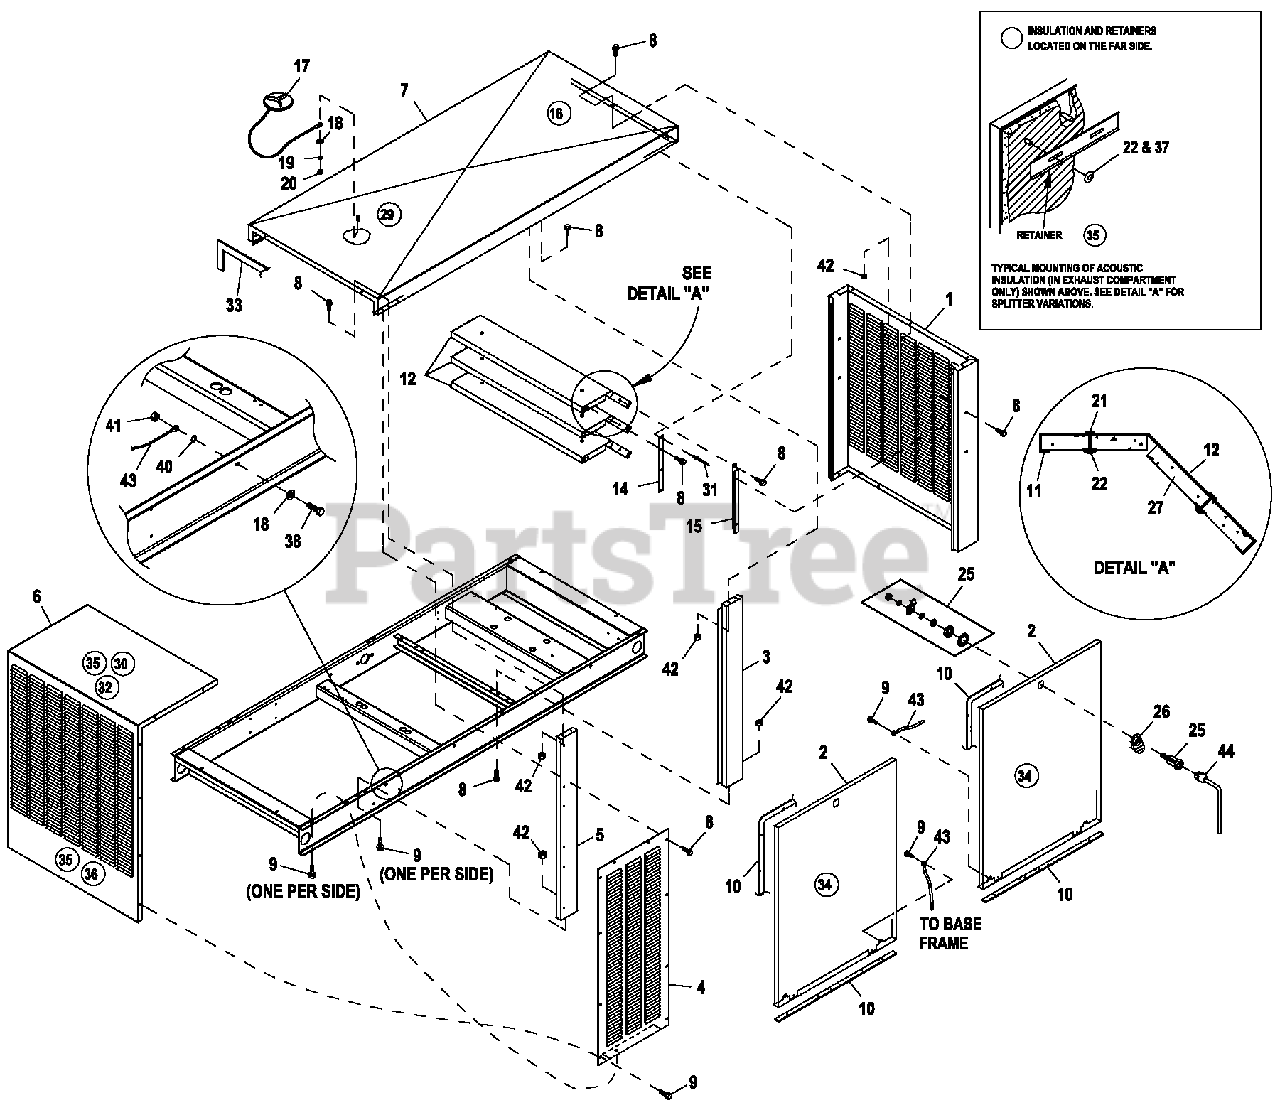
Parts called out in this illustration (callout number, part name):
1	REAR WRAP AL
2	DOORAL
3	CENTER SUPPORT AL
4	DUCT.DISCHRGAL
5	FRONT CRNR AL
6	DUCT. CNTR DISCHRG AL
7	ROOF. AL
8	SCREW THF M6-1 X 16 N WA Z/JS
9	SCREW TH-FRM M6 W/CAP SHKPRF W
10	GASKET EXTRUDED TRIM (547" LG)
11	INSUL SPLITTER SMALL
12	SPLITTER
14	STRINGER SPLITTER C3
15	SUPPORT SPLITTER C5 130KW
16	INSUL ROOF TOP REAR
17	ASSEMBLY COVER ACCESS
18	WASHER FLAT 1/4-M6 ZINC
19	WASHER LOCK M6-1/4
20	NUT HEX 1/4-20 STEEL
21	INSULATION RETAINMENT HANGER
22	WASHER SELF LOCKING DOME #4-40
25	VISE-ACTION LATCH SLOTTED CIR
26	TAB PULL
27	INSULATION SPLITTER
29	INSULATION ROOF TOP
30	INSULATION DUCT TOP
31	RIVET POP.1875 X .450 SS
32	REFLECTIVE HEAT SHIELD 2.4L
33	STRIP SEALANT 1/8X1 (44.5"LG)
34	INSULATION DOOR
35	RETAINER INSULATION (820)
36	INSULATION DUCT FRONT
37	WASHER SELF LOCKING DOME #8-32
38	SCREW HHC M6-1.0X20 G8.8
40	WASHER SHAKEPROOF INT 1/4
41	NUT HEX M6X1.0 G8 YELCHR
42	NUT HEX LOCK M6-1.0 SS NY INS
43	ASSY WIRE 14 AWG 34.8" GRN/YEL
44	KEY VISE-ACTION LATCH SLOT CIR
